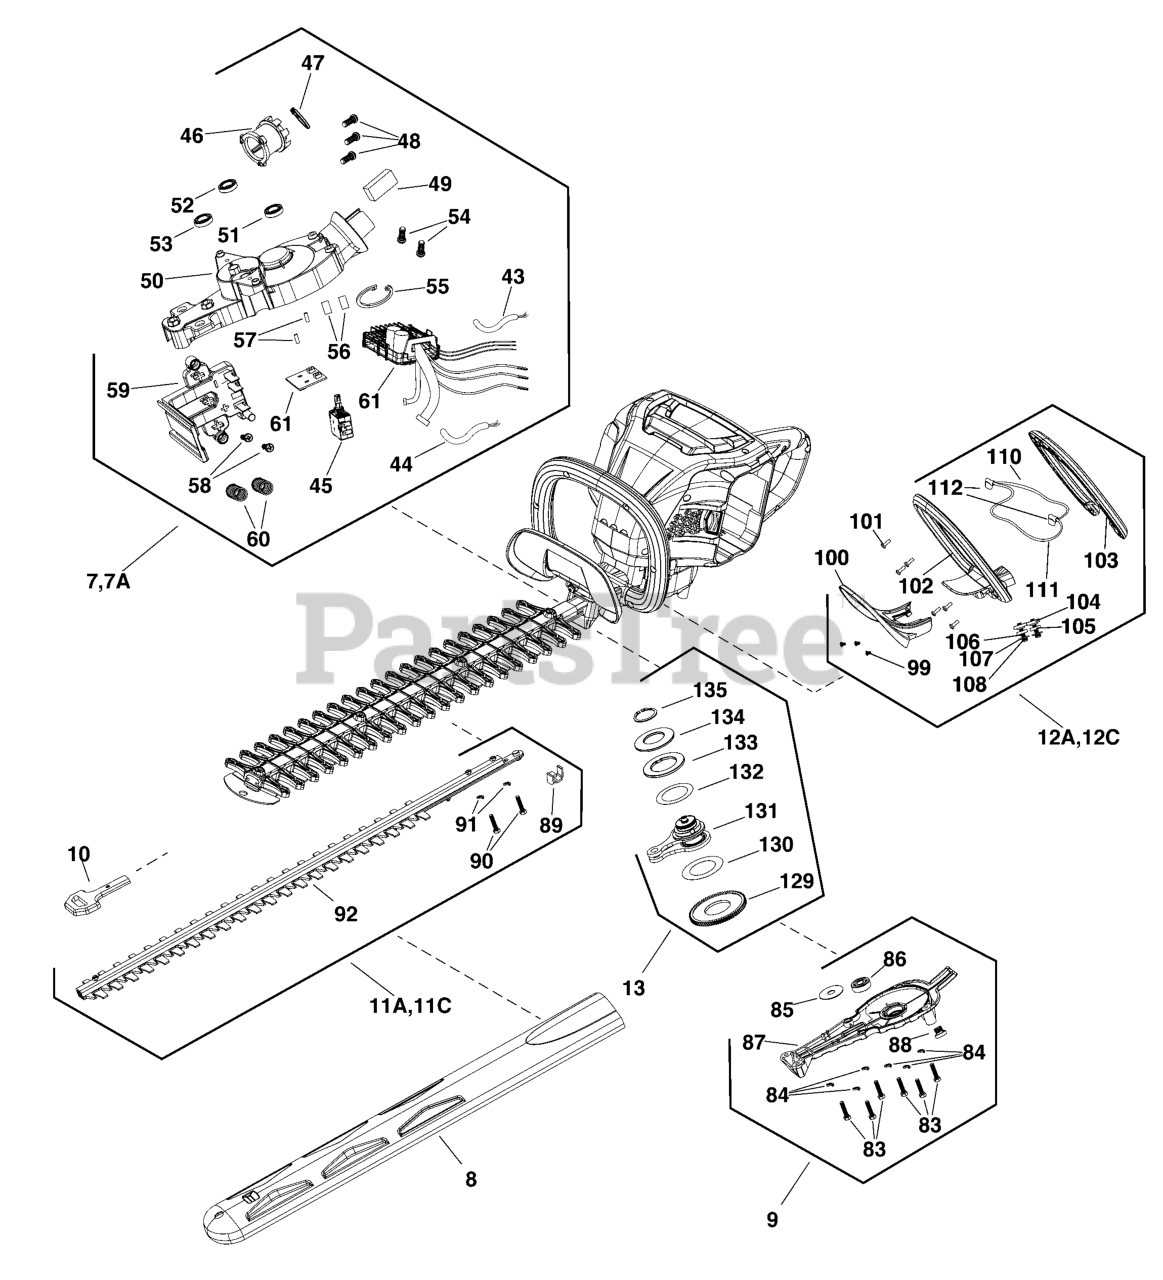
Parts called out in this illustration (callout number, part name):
7	KIT, ELECTRIC & ON/OFF CIRCUIT CARD, NA
7A	KIT, ELECTRIC & ON/OFF CIRCUIT CARD, AU & EU
9	KIT, GEAR CASE
10	GUARD, TIP
11A	KIT, BLADE ASSEMBLY, NA
11C	KIT, BLADE ASSEMBLY, EU
12A	KIT, HANDLE & GUARD ASSEMBLY, NA
12C	KIT, HANDLE & GUARD ASSEMBLY, EU
13	KIT, CONNECTING ROD ASSEMBLY
43	SHRINK TUBE
44	SHRINK TUBE
46	ROTATING SLEEVE
47	PAD
48	SCREW
49	PAD
50	COVER, GEAR
51	BEARING, BALL
52	BEARING, BALL
53	BEARING, BALL
54	SCREW
55	C-CLIP
56	PAD
57	PIN
58	SCREW
59	INSERT
60	SPRING
61	CIRCUIT BOARD
83	SCREW
84	GASKET
85	GASKET
86	BEARING, BALL
87	COVER, GEAR BOX
88	PAD
89	BRACKET
90	SCREW
91	GASKET
92	BLADE
99	SCREW
100	GUARD
101	SCREW
102	HANDLE COVER
103	HANDLE COVER
104	PAD
105	PAD
106	SCREW
107	GASKET
108	GASKET
110	WIRE, Red
111	WIRE, Black
112	MICROSWITCH
129	GEAR, Drive
129	GEAR, CAM
130	GASKET
131	CAM, GEAR
132	GASKET
133	RING, LINK
134	RING, COMPRESSION
135	STRAP
